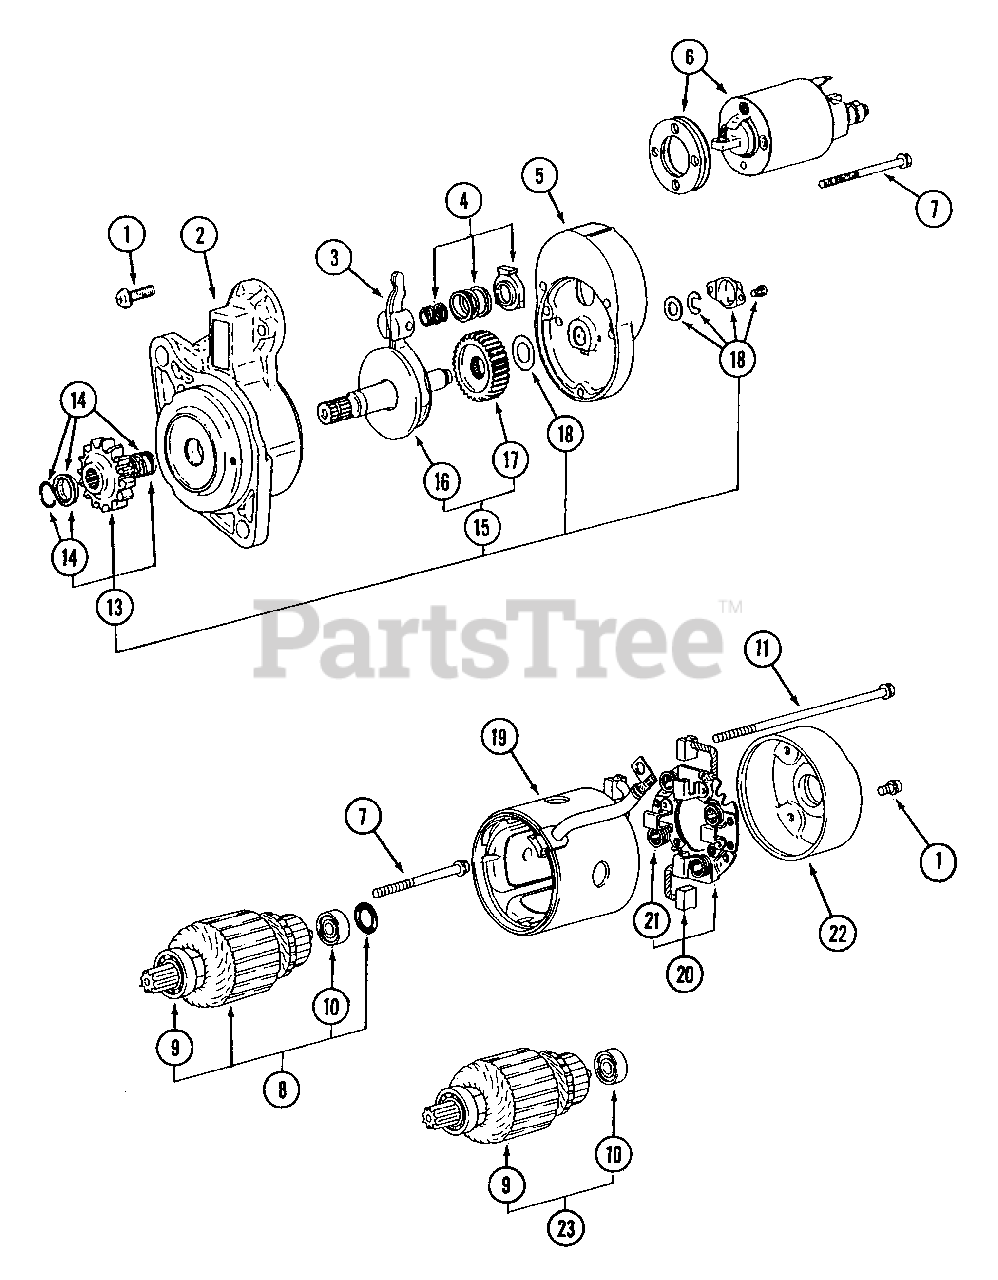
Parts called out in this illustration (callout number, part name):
2	Front Bracket Ass'y.
3	Lever Ass'y.
5	Center Bracket Ass'y.
6	Switch Ass'y.
8	Armature Set
14	Stopper Set
16	Pinion Shaft Ass'y.
19	Yoke Ass'y.
20	Brush Holder Ass'y.
21	Spring, Brush
22	Bracket, Rear
23	Service Kit, Starter Bearing
